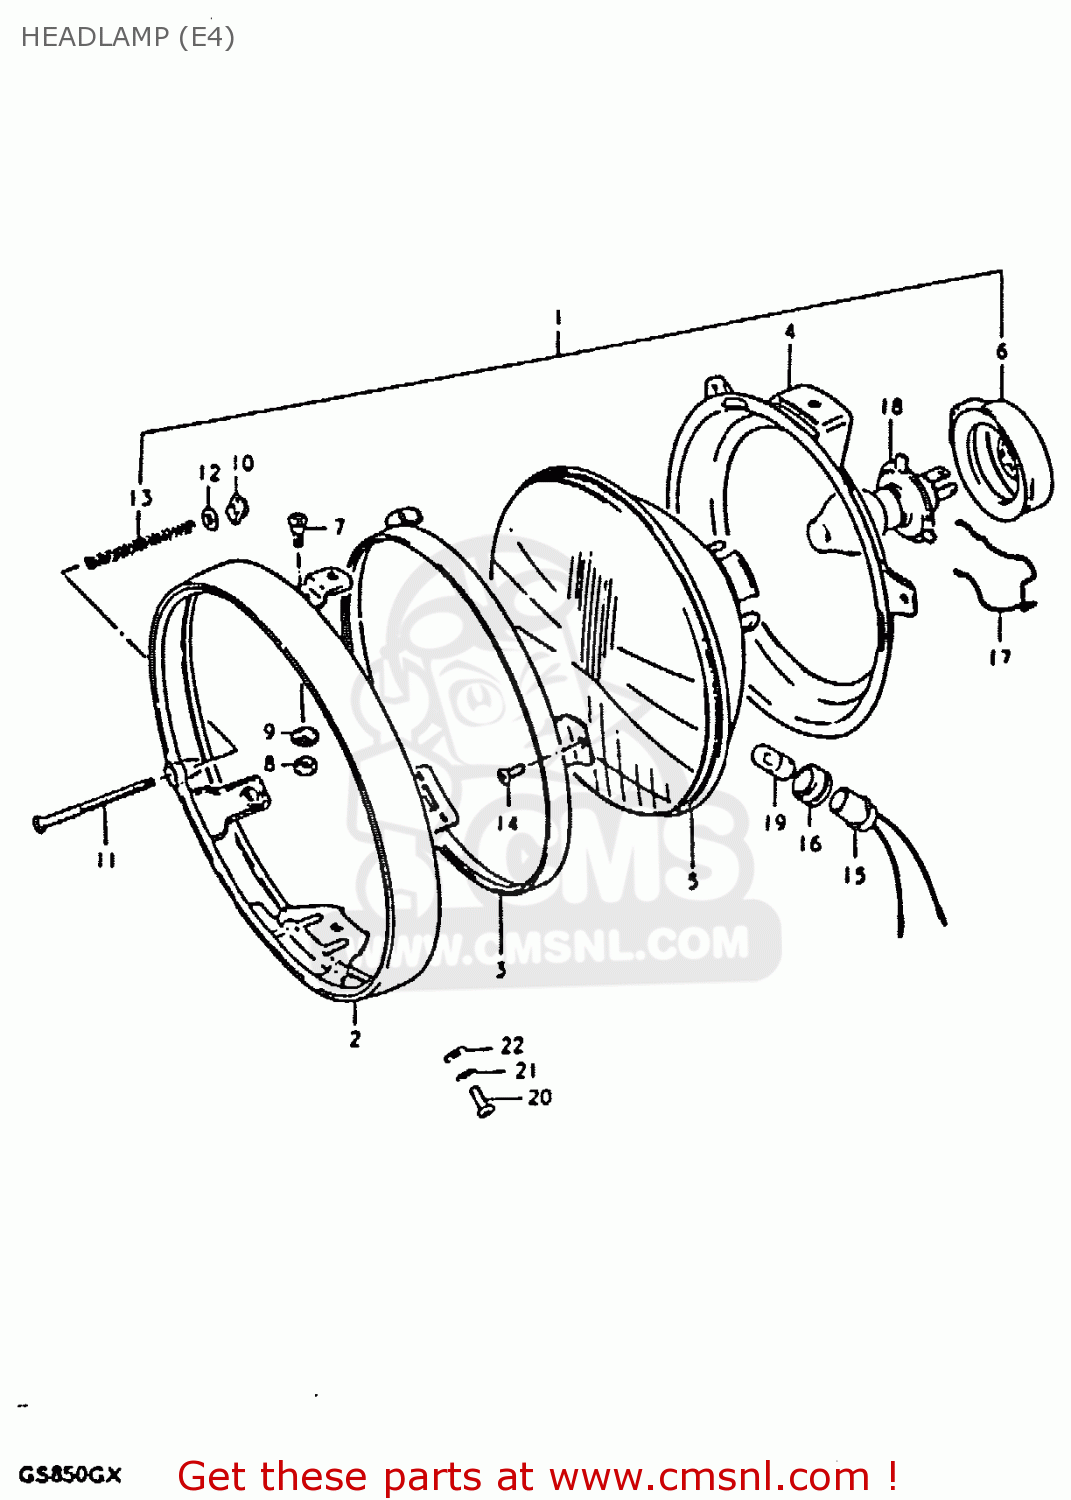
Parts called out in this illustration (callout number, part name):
1	HEADLAMP ASSY
2	RIM
3	RETAINER
4	RING,HEADLAMP UNIT
5	UNIT,HEAD LAMP
6	COVER,HEADLAMP SOCKET
7	SCREW
8	NUT,ADJUSTING
9	SPACER
10	NUT
11	SCREW,HEADLAMP ADJUST
12	WASHER
13	SPRING,HEADLAMP ADJUST
14	SCREW
15	SOCKET
16	JOINT,RUBBER
17	CLAMP,HEADLAMP SOCKET
18	BULB (12V, 60/55W, H4)
19	BULB(12V4W)
20	SCREW
21	WASHER,LOCK
22	WASHER
